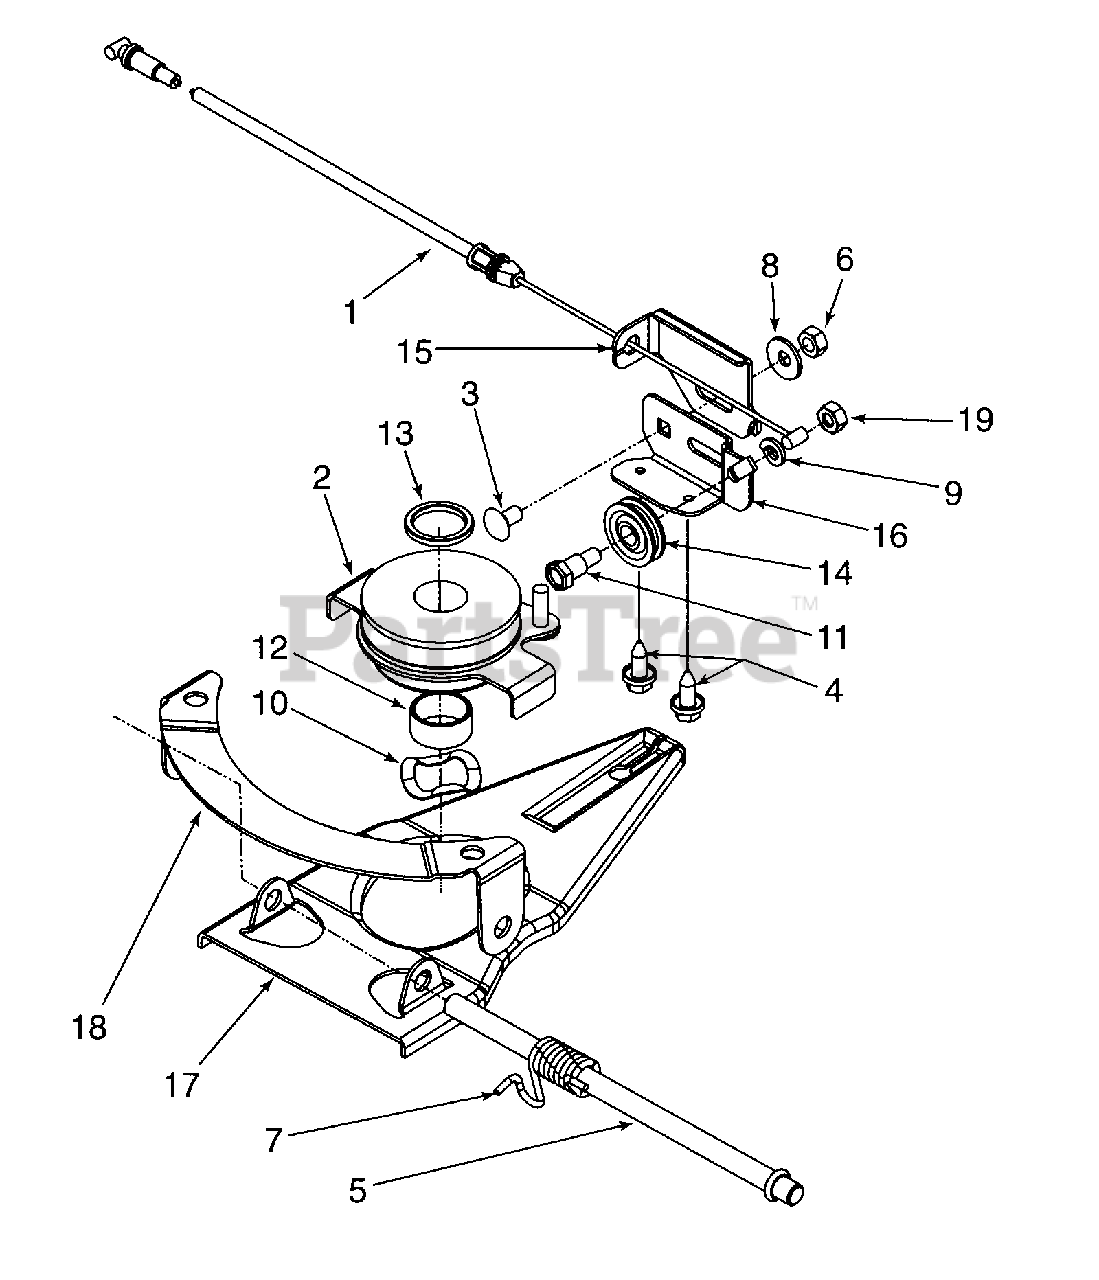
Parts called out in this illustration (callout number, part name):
1	6 Spd. Cable
2	Pulley Ass'y Multi- Spd.
3	Scr. 1/4-20 x .50 Carr.
4	Scr. AB 1/4-14 x .625 Hxinwsh
5	Pivot Shaft
6	Nut 1/4-20
7	Torsion Spring LH
8	Bell Wash. .265 x .75 x .062
9	Lock Wash. 1/4 Reg Duty
10	Wave Wash. 1.38 x .88 x .029
11	Shld.Scr. .375 x 1/4-14AB
12	Slev Spcr .88 ID x 1.00 OD x .48
13	Slev Spcr .88 ID x 1.131D x .12
14	Roller Cable
15	6 Spd. Cable Adj. Bracket
16	6 Spd. Cable Mt. Bracket
19	Hex Nut 1/4-28
